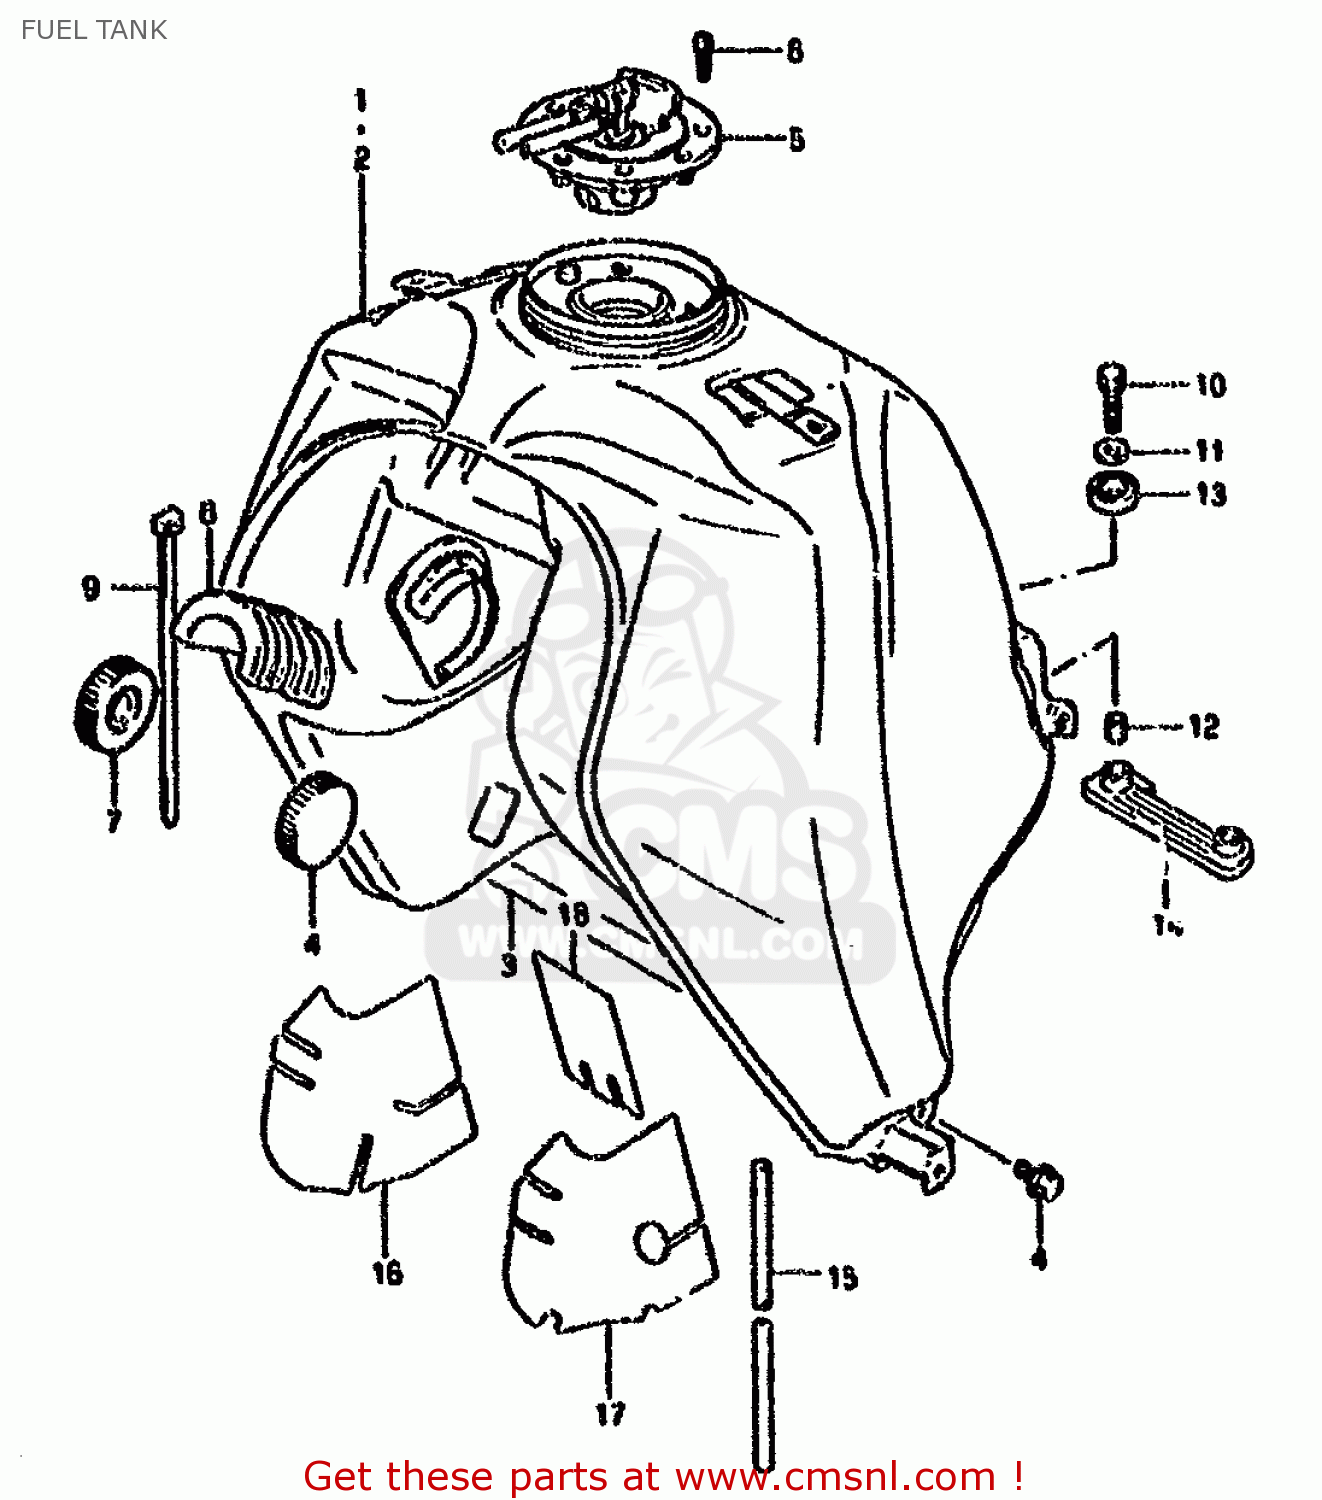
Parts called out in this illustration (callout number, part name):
1	TANK ASSY,FUEL (BLACK)
2	TANK,FUEL BLACK
3	TUBE, FUEL TANK
4	BOLT
5	CAP SET,FUEL TANK
6	BOLT(5X20)
7	CUSHION,FUEL TANK FR
8	CUSHION, UPPER
9	CLAMP(L:250)
10	BOLT
11	WASHER
12	SPACER
13	CUSHION,FUEL TANK RR UPR
14	CUSHION FUEL T
15	HOSE(7X10.2X2000)
16	HEATSHIELD,FUEL TANK,R
17	HEATSHIELD,FUEL TANK,L
18	HEATSHIELD,FUEL TANK CTR
